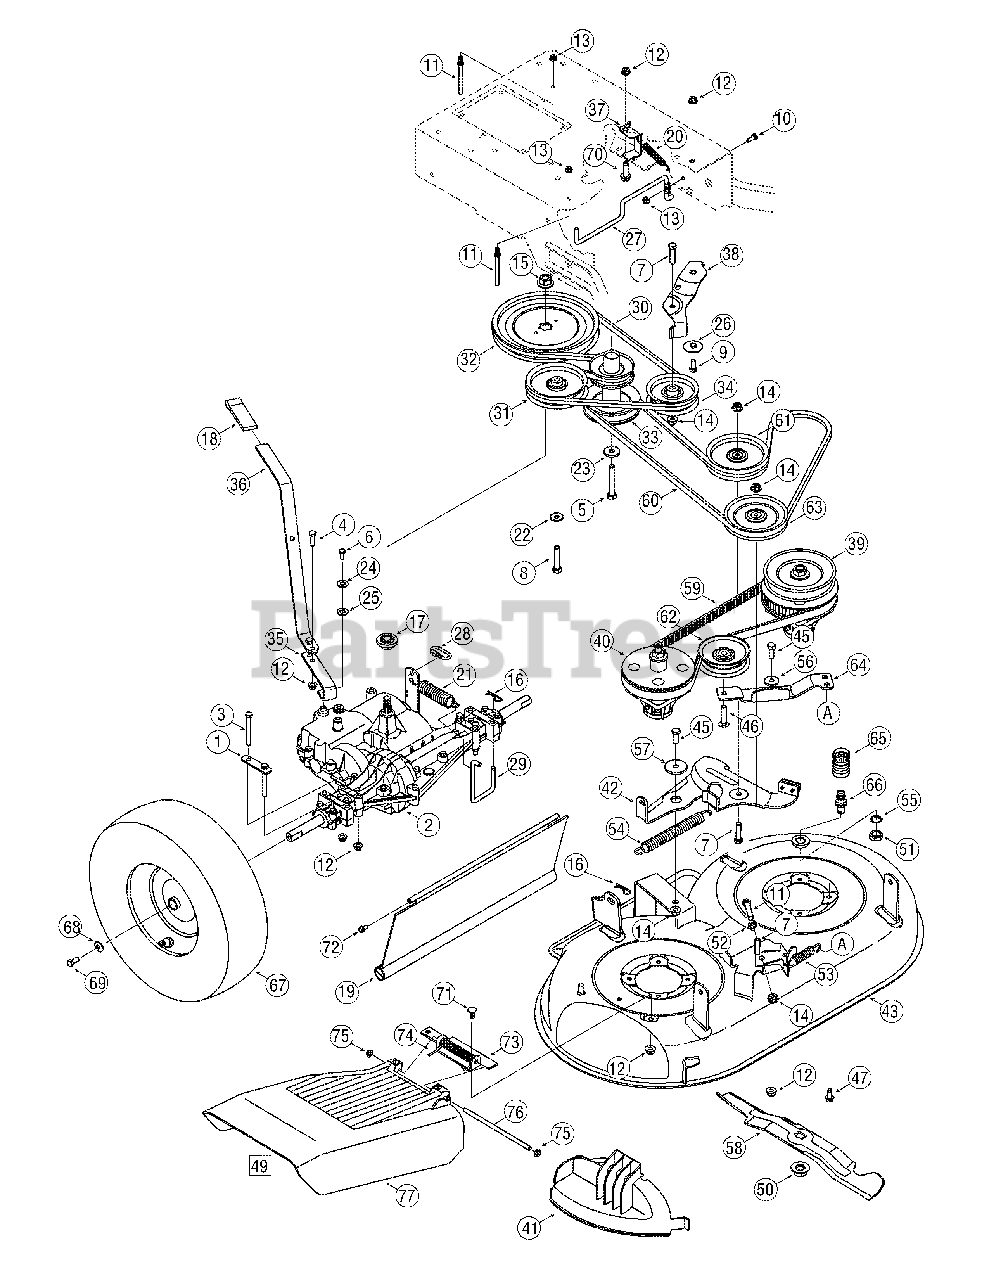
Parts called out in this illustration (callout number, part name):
2	Transmission 4-Speed
3	Screw, HH Cap: 5/16-18 x 2.75"
4	Screw, HH Cap: 5/16-18 x 1.00"
5	Screw, HH Cap: 7/16-20 x 2.75"
6	Screw, HH Cap: 1/4-28 x .625"
7	Screw, HH Cap: 3/8-16 x 1.50"
8	Screw, HH Cap: 3/8-16 x 1.75"
9	Screw, HH Cap: 5/16-18 x .75"
10	Screw, HH Cap: 1/4-20 x .75"
11	Belt Keeper
12	Nut, Flange Lock: 5/16-18
13	Nut, Flange Lock: 1/4-20
14	Nut, Flange Lock: 3/8-16
15	Nut, Flange: 9/16-18
16	Hairpin Clip: 092" x 1.64" Long
17	Pulley Hub
19	Trailing Shield
20	Extension Spring
21	Extension Spring
22	Washer, Spring: .401" x .870" x .063"
23	Washer, Flat: 450" x 1.250" x .164"
24	Washer, Bell
25	Washer, Flat: .39" x .87" x .06"
26	Spacer, Shoulder: .50" x .1475"
28	Loop Link Coupling
29	Trans Mount Rod
30	Belt, V Type
31	Idler Pulley: 4.25" Dia.
32	Flat Sheave 7.75"
33	Engine Pulley 3.20" x 4.35" Dia.
34	Idler Pulley 3.50" Dia.
39	Drive Spindle Assembly
40	Spacer Spindle Assembly
41	Mulch Plug
42	Idler Arm Assembly
44	Bolt, Carriage: 5/16-18 x .75"
45	Screw, HH Cap: 3/8-16 x 1.00"
46	Screw, Carriage: 3/8-16 x 1.75"
47	Screw, LD: 5/16-18 x .750"
48	Screw, HH Cap: 3/8-16 x 2.00"
49	Chute Deflector Assy
50	Nut, Flange: 5/8-18
51	Nut, Hex
52	Nut, Hex 3/8-16
53	Extension Spring: Timing Belt Tension
54	Extension Spring: Deck Brake
55	Washer, Lock
56	Spacer, Shoulder: .625" x .169"
57	Spacer, Shoulder: .884" x .190"
58	Blade: 17.9"
59	Belt, Timing
60	Belt, V Type
61	Idler Pulley 4.25"
62	Idler Pulley 3.50"
63	Idler Pulley V-Type 5.0"
65	Water Nozzle Adapter
66	Water Nozzle
67	Wheel 16 x 4 x 8
68	Washer, Bell: .340" x .872" x .060"
69	Screw, HH Cap: 5/16-24 x .75"
70	Screw, TT: 3/8-16 x 1.25"
71	Screw, Carriage: 5/16-18 x 1.00"
72	Screw, HL: 1/4-15 x .50"
74	Deflector Torsion Spring
75	Push Cap
76	Deflector Pin
77	Chute Deflector, 33" SD Deck
